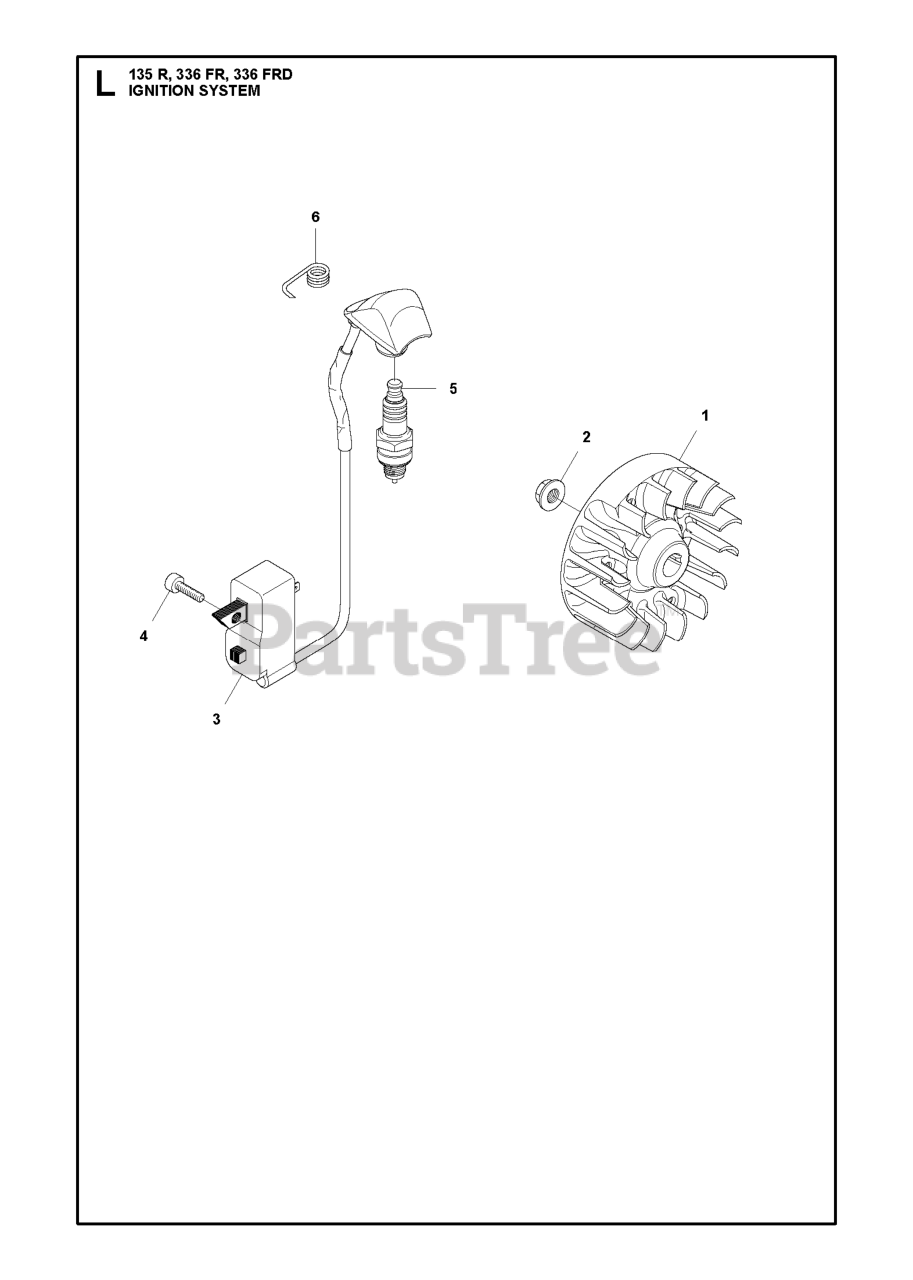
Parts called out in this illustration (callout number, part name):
1	FLYWHEEL
2	FLANGE NUT
3	IGNITION MODULE OPS
5	SPARK PLUG RCJ6Y NLA
